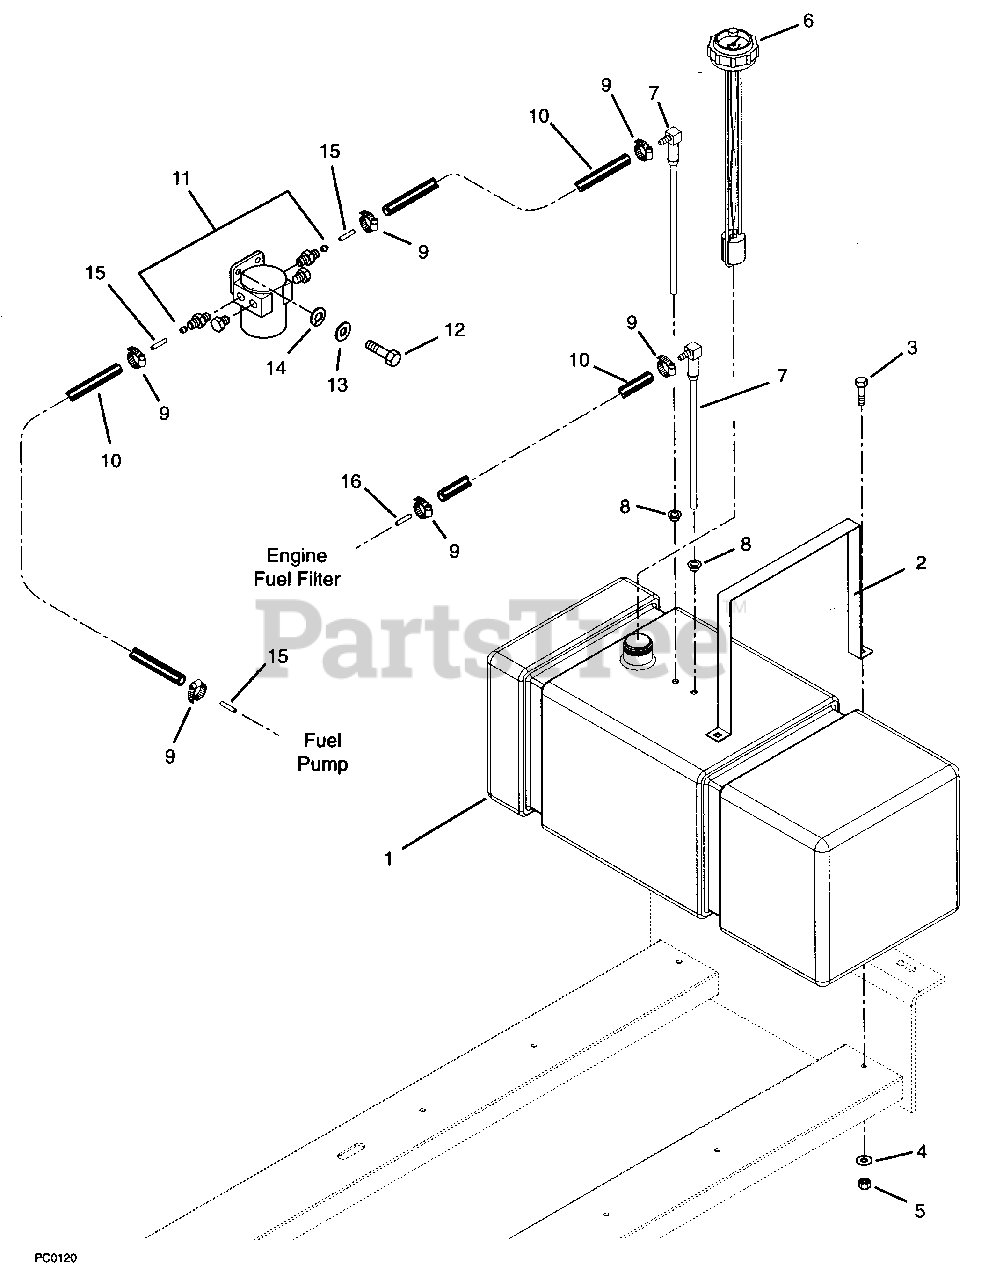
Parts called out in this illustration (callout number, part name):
1	Fuel Tank
2	Fuel Tank Strap
3	Bolt-Hex .38-16 x 1.75
4	Washer-Flat-Steel .438 x 1.0 x .083
5	Nut-Locking .375-16
6	Gauge-Fuel
7	Fitting-Tank
8	Bushing
9	Clamp-Hose
10	Bulk Gas Line
11	Fuel Filter-Perkins
12	Bolt-Hex .31-18 x 1.00
13	Washer-Flat-Steel .312 x .734 x .065
14	Washer-Lock .250 x .077
15	Tubing 5/16" OD x .028 Wall x 1.5
16	Tubing 1/4" OD x .028 Wall x 1.5
